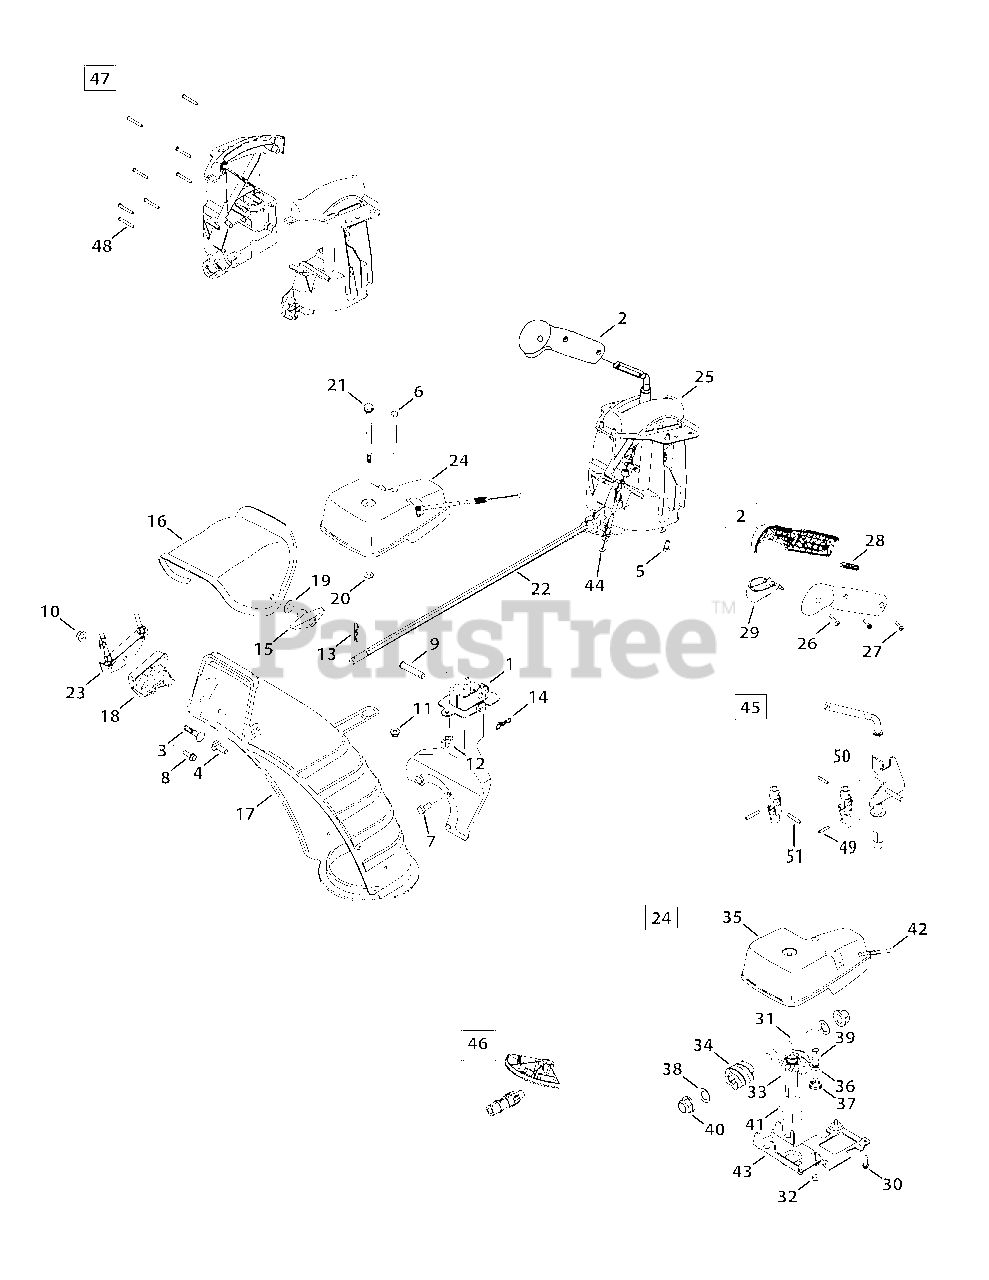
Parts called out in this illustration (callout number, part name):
1	Chute Support Bracket
2	Handle Assembly
3	Bolt, Carriage, 5/16-18 x 1.50
4	Bolt, Carrier, 5/16-18 x 1.00
5	Screw, HL, 1/4-15 x 0.50
6	Hex Head Screw, 1/4-20 x 3.00
7	Hex Head Screw, 5/16-24 x .750
8	Screw, HL, 1/4-15 x 0.750
9	Clevis Pin, 3/8 x 1.87
10	Nut, Flangelock, 5/16-18
11	Nut, Flangelock, 1/4-20
12	Wing Nut, 1/4-20
13	Internal Cotter Pin
14	Bow-Tie Cotter Pin
15	Wing Knob, 5/16-18
16	Chute, Upper
17	Chute, Lower
18	Cable Guide, Chute Tilt
19	Washer, Flat, .349 x .879
20	Washer, Flat, .25 x .630
21	Screw, Shoulder, .312 x 3.5 x 1/4-20
22	Chute Rod, 3/8 Hex
24	Gearbox Assembly, Chute Rotation
25	Chute Control, 4-Way
26	Screw, #8 x 1.00
27	Screw, 8-32 x .750
28	Joystick Plug
29	Joystick Trigger
30	Screw, 12-16 x .75
31	Hex Shaft
32	Hexlock Nut, 1/4-28
33	Gear, 14 T
34	Worm
35	Gear Cover
36	Pawl Lock
37	Torsion Spring, .721 ID x .474
38	Washer, Flat, .625 x 1.0 x .067
39	Screw, Shoulder, .340 x .950 x 1/4-28
40	Hex Bearing
41	Flange Bearing
42	Cable Lock
43	Gear Bracket
44	4-Way Cable
44	4-Way Cable w/Clip
45	Shift Assembly
46	Gear Set Assembly
47	Handle Housing Assembly
48	Screw, #8-18 x 1.250
49	Pin, Roll
50	Block, Asm Joint
51	Pin, Roll
